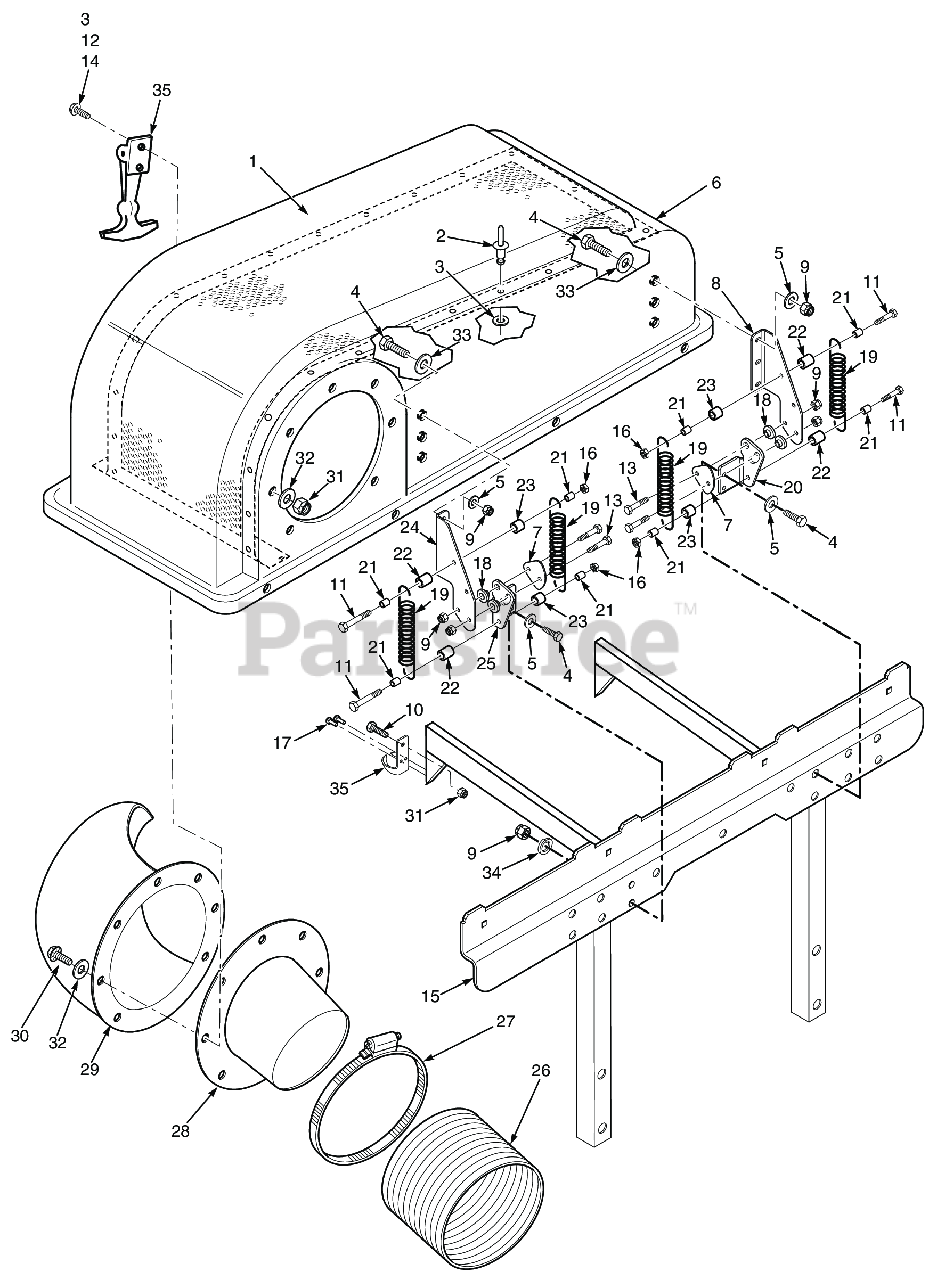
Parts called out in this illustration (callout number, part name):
1	Screen, Catcher Hood
2	Pop Rivet, 3/16 x .652"
3	Flatwasher, 3/16 (.196 x .469 x .048)
4	Bolt, Hex Head 3/8-16 x 1-1/4", Kawasaki FX / FS
5	Flatwasher, 3/8-.391 x .938 x .105
6	Hood Assembly, GC-STT
7	Guard, GC Hinge
8	Hinge, Upper LH
9	HEX NUT, ELASTIC STOP LOCK, 3/8-16
10	BOLT, SERRATED FLANGE HEX HEAD 5/16-18 X 3/4"
11	Capscrew, Hex Head 3/8-16 x 3-3/4"
12	HEX NUT, ELASTIC STOP LOCK # 10-32
13	Bolt, Hex Head, 3/8-16 x 1-1/2"
14	Screw, #10-32 x 3/4"
15	Support Weldment, Bag Frame
16	Bolt, Hex Head 3/8-16 x 1" Ser. Flg.
17	Rivot, 3/16 x .402 POP
18	Bushing, Hopper Pivot
19	Spring, Hood Hinge
20	HINGE, LOWER LH
21	Spacer, Deck Assist
22	Spacer
23	SPACER, J-PULL ROD
24	Hinge, Upper RH
25	HINGE, LOWER RH
26	Hose, 8.00" Dia. x 53" Long
27	Clamp, 8-5/8" Max Dia. (61")
28	Tube, Filler (8" Hose)
29	Elbow (8" Hose)
30	Bolt, 5/16 - 18 x 1 - 1/4" Hex Head
31	HEX NUT, ELASTIC STOP LOCK, 5/16-18
32	Flatwasher, 5/16-.375 x .875 x .083 (35BV & 37BV-EFI)
33	Flatwasher, 3/8-.406 x 1-1-1/2 x 7 Gauge
34	Lockwasher, 3/8" Spring, Kawasaki FX / FS
35	Latch, Hopper
